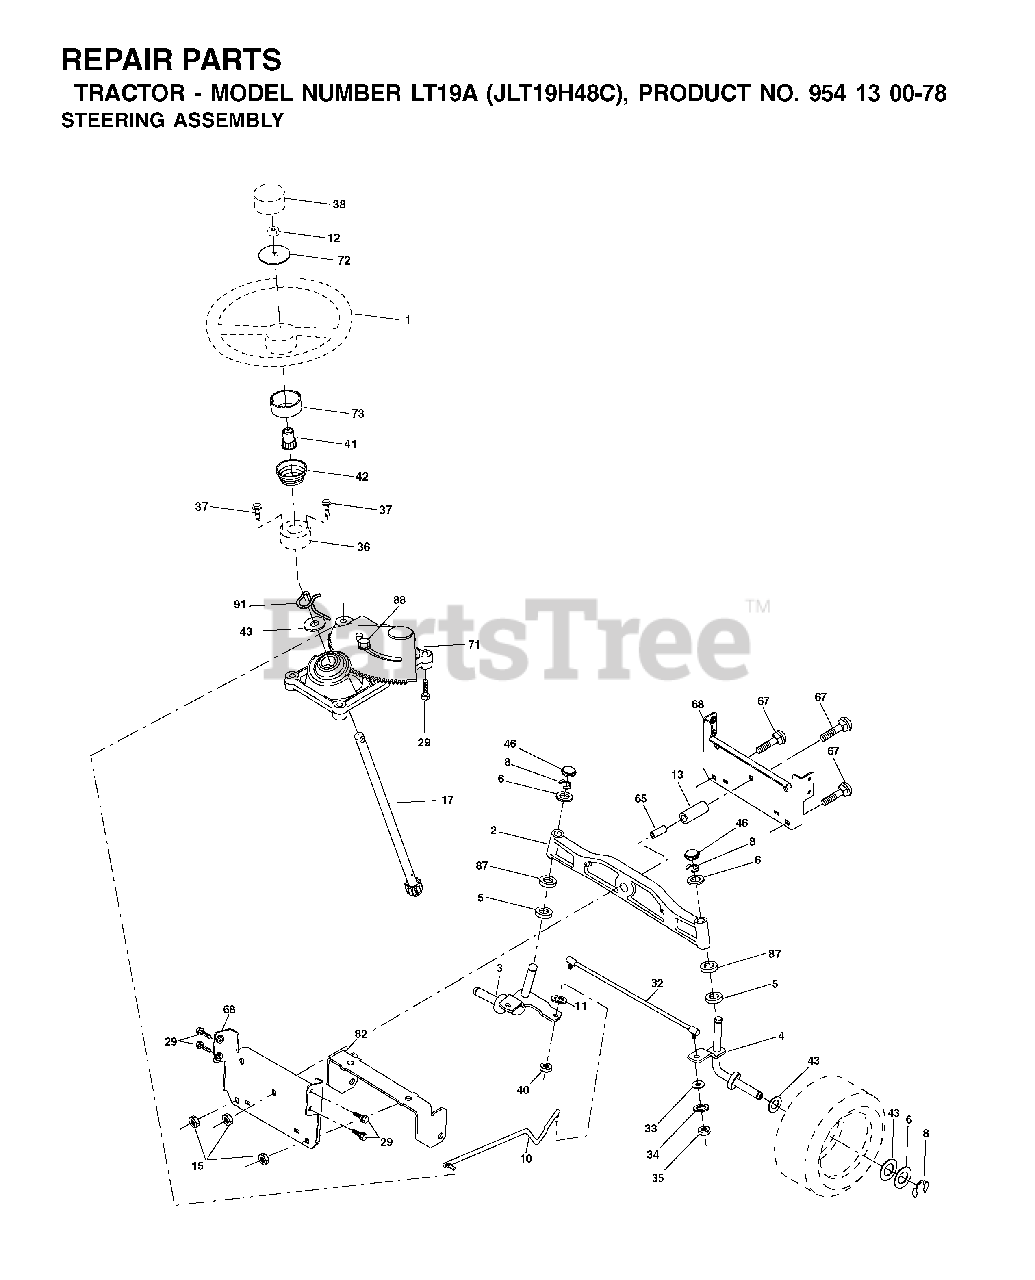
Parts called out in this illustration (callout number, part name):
2	AXLE ASM
3	SPINDLE.ASM.LH.15"TIRES
4	SPINDLE.ASM.RH.15"TIRES
8	RING CLIP
10	DRAGLINK.15".TIRES.2001
11	WASHER, LOCK 3/8
12	NUT.HEX.1/2-20
13	TUBE, PIVOT AXLE
15	NUT
17	SHAFT ASM STRG
29	SCREW 3/8-16X3/4
32	ROD.ASM.TIE.BALL.JOINT.NOVAN
33	WASHER M
34	LOCKWASHER
35	NUT, CROWNLOCK
36	BUSHING, STRG. BLK
40	GRIPCO NUT
41	STEERING WHEEL ADAPTOR
46	CAP.SPINDLE
65	SPACER BRACE AXLE
67	BOLT
68	BRACE.AXLE.15"TIRES
71	STEERING ASM
82	BRACKET
87	WASHER, FLAT .781 X 1 1/2"
88	BOLT, SHOULDER 7/16-20
91	CLIP.STEERING
